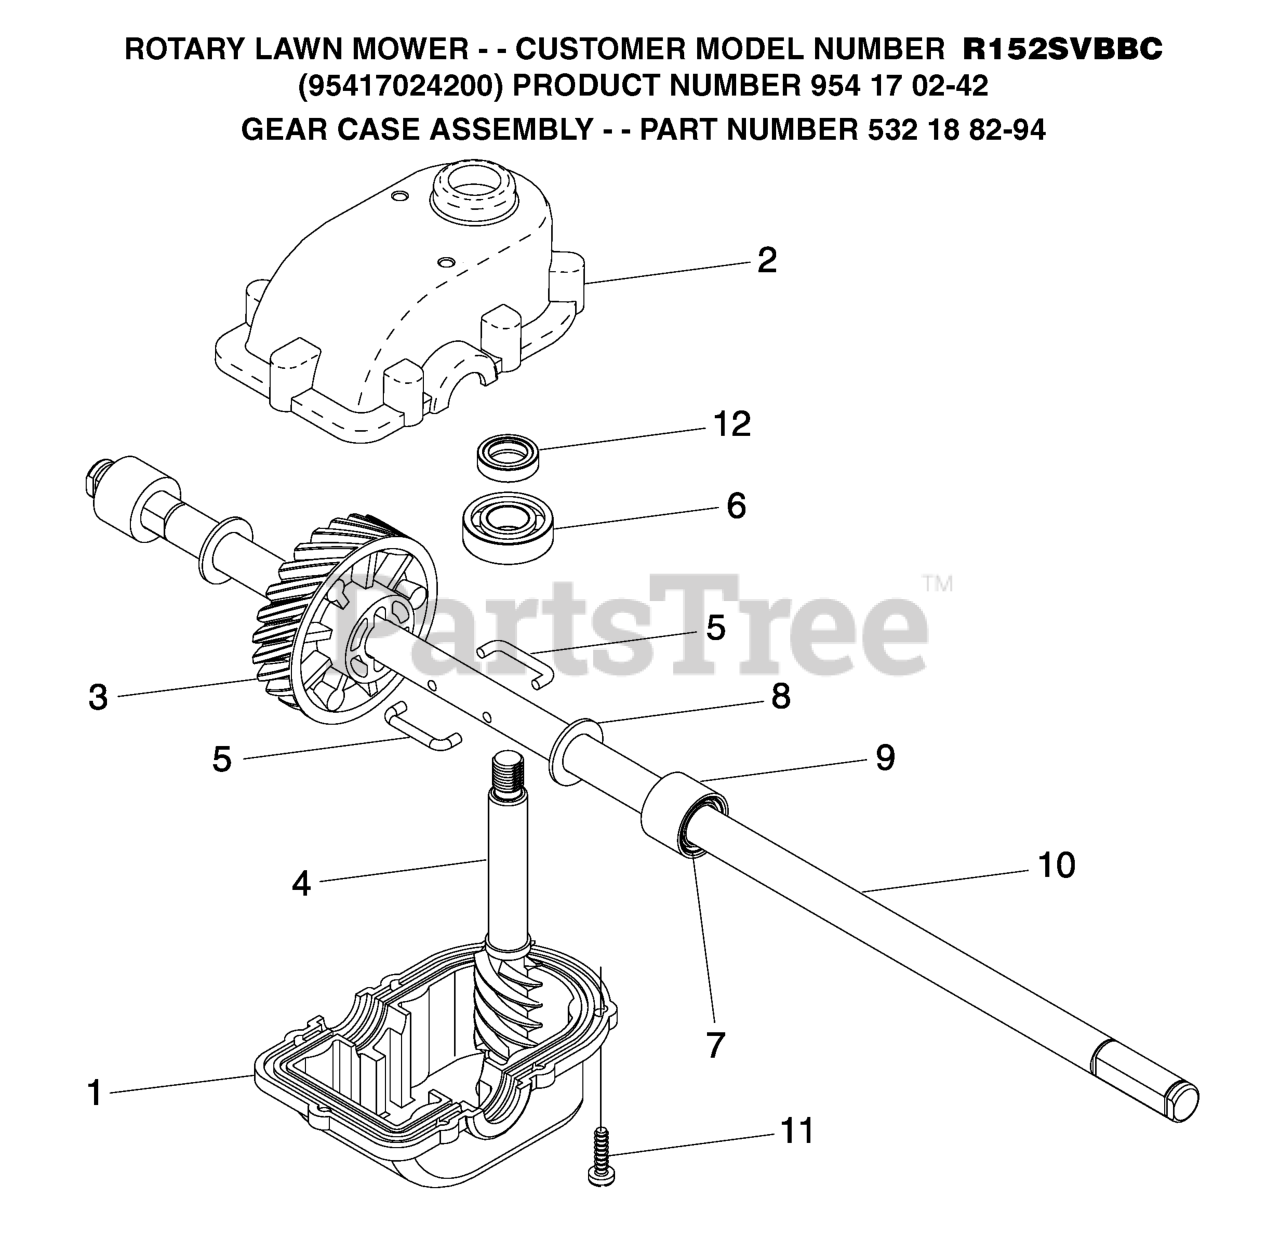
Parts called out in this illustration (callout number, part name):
1	CASE, LOWER
2	GEARCASE.HOUSING
3	GEAR.24.TOOTH.WALK.MOWER
5	WIRE, FORMED (15966)
7	SEAL.OUTPUT.SHAFT
10	SHAFT OUTPUT
12	SEAL INPUT SHAFT
